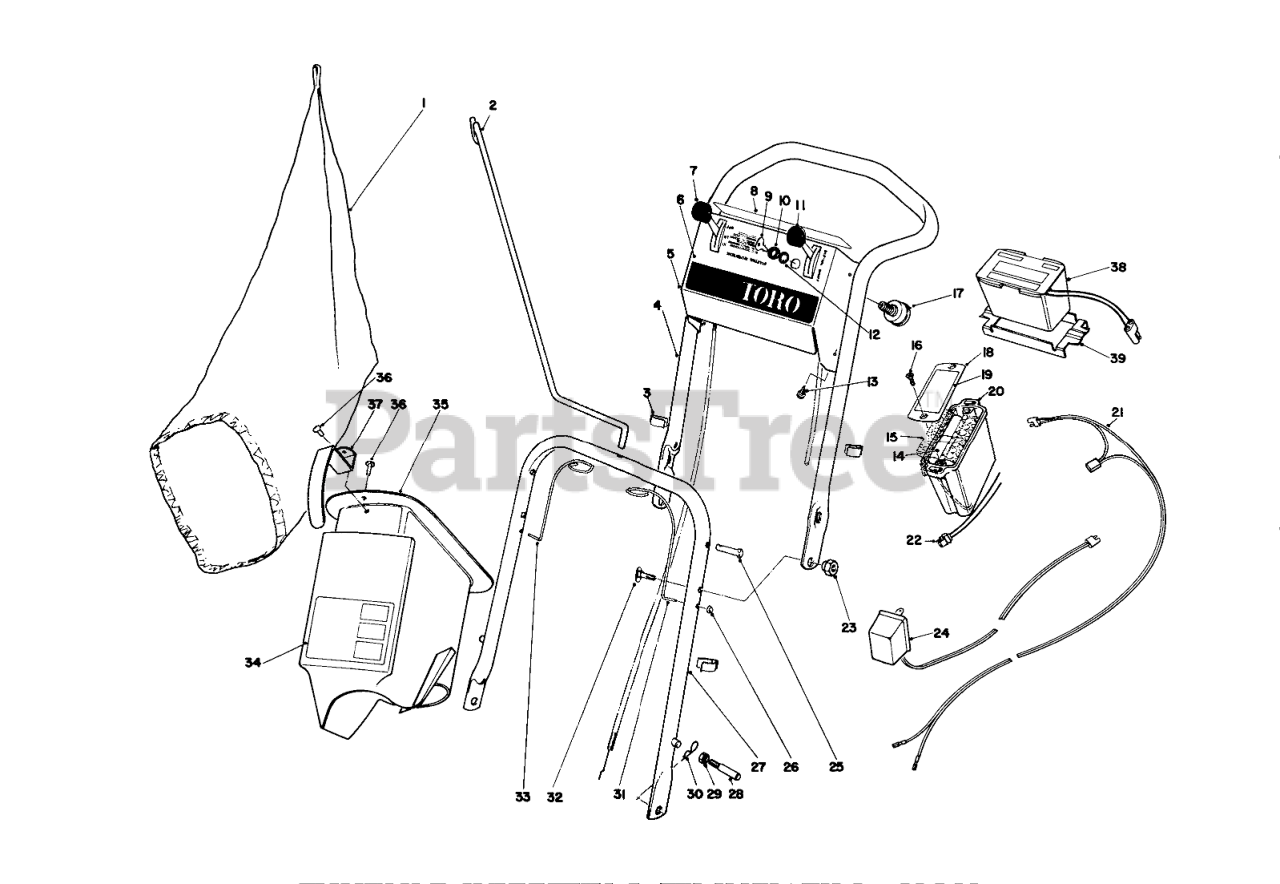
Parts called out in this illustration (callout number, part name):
1	BAG REPLACMNT44-0540
2	Bag Rod
3	BOWDEN CLIP
4	Upper Handle
5	Control Plate
6	Decal-Control Plate
7	Control Throttle
8	Decal, Safety
9	Key
10	NUT-HH
11	Traction Control
12	WASHER-TOOTH, INTERNAL
13	SCREW-HWHTF
14	Battery Pack
15	Spacer
17	STARTER SWITCH
18	Cover
19	Decal
20	Container Pack
21	Wiring Harness
22	Plug & Wire
23	Pivot Nut
24	Charger
25	Latch Pin
27	Lower Handle
28	HANDLE PIN
29	Nut
30	PIN-COTTER, HAIR
31	Latch Spring L.H.
32	HANDLE SCREW
33	Latch Spring R.H.
34	Decal Instructions
35	Grass Chute (Incl. Ref. #34, 36-37)
37	HANDLE-GRASS CHUTE
38	Battery
39	Adapter
